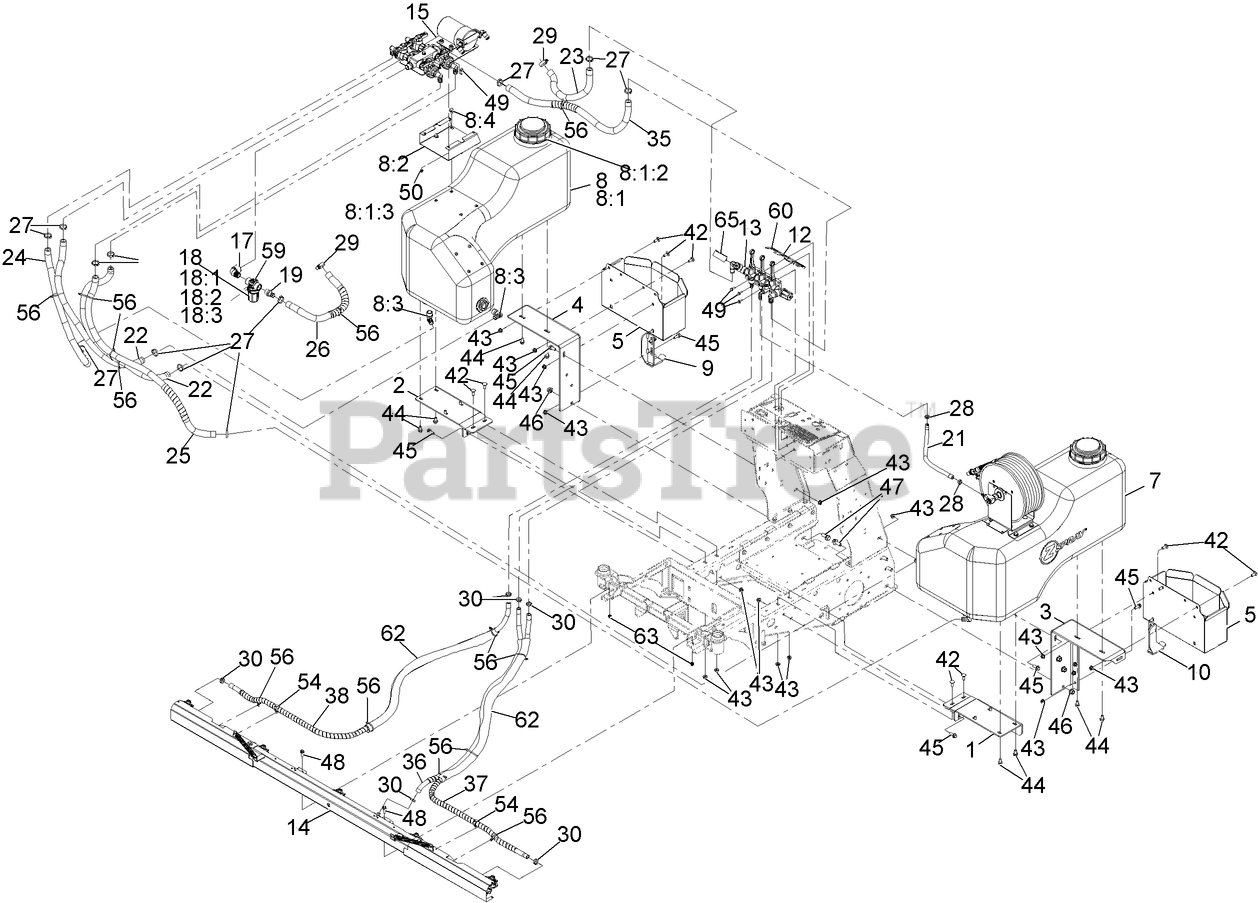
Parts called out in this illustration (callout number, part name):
1	Mount-Tank, LH Wing
2	Mount-Tank, RH Wing
3	Mount-Box, Lt Fert
4	Mount-Box, Rt Fert
5	BOX-FERT, MAX
7	ASM-Tank, Hose Reel
8	ASM-Tank, Rt
8:1	ASM-TANK, RT
8:1:2	CAP-TANK, SPRAY
8:1:3	Fitting-Bulkhead
8:2	PLATFORM, LIQUID VALVE MO
8:3	FITTING-ELBOW, 90
8:4	Screw-HHF
9	Bracket-Anti-Tip Rt
10	Wldmt-Bracket-Anti-Tip Lt
12	Bracket-Manifold
13	ASM-Manifold
14	ASM-Boom, Spray
15	ASM, Liquid Valve
17	ELBOW-90DEG
18	STRAINER-INLINE
18:1	BOWL-STRAINER
18:2	GASKET-HEAD, LINE STRAINE
18:3	Screen-Strainer, 50 Mesh
19	HOSEBARB
21	Hose-Spray
22	Hose-Spray
23	Hose-Spray
24	Hose-Spray
25	Hose-Spray, Wrapped
26	Hose-Spray, Wrapped
27	Clamp-Oetiker, 167
28	CLAMP-OETIKER, 167
29	CLAMP-HOSE
30	CLAMP-OETIKER, 167
35	Hose-Spray, Wrapped
36	HOSE-SPRAY, WRAPPED
37	HOSE-SPRAY, WRAPPED
38	HOSE-SPRAY, WRAPPED
42	SCREW-CARR
43	Nut-Hex Flange
44	SCREW-HHF
45	SCREW-HHF
46	NUT-HEX FLANGE
47	SCREW-HHF
48	SCREW-HHF
49	Screw-HHF
50	Nut-Hex Flange
54	CLIP-TIE
56	TIE-CABLE
59	DECAL-CAP, STRAINER
60	Decal-Valve, Boom
62	Guard-Mesh
63	Nut-Hex Flange
65	GAUGE
